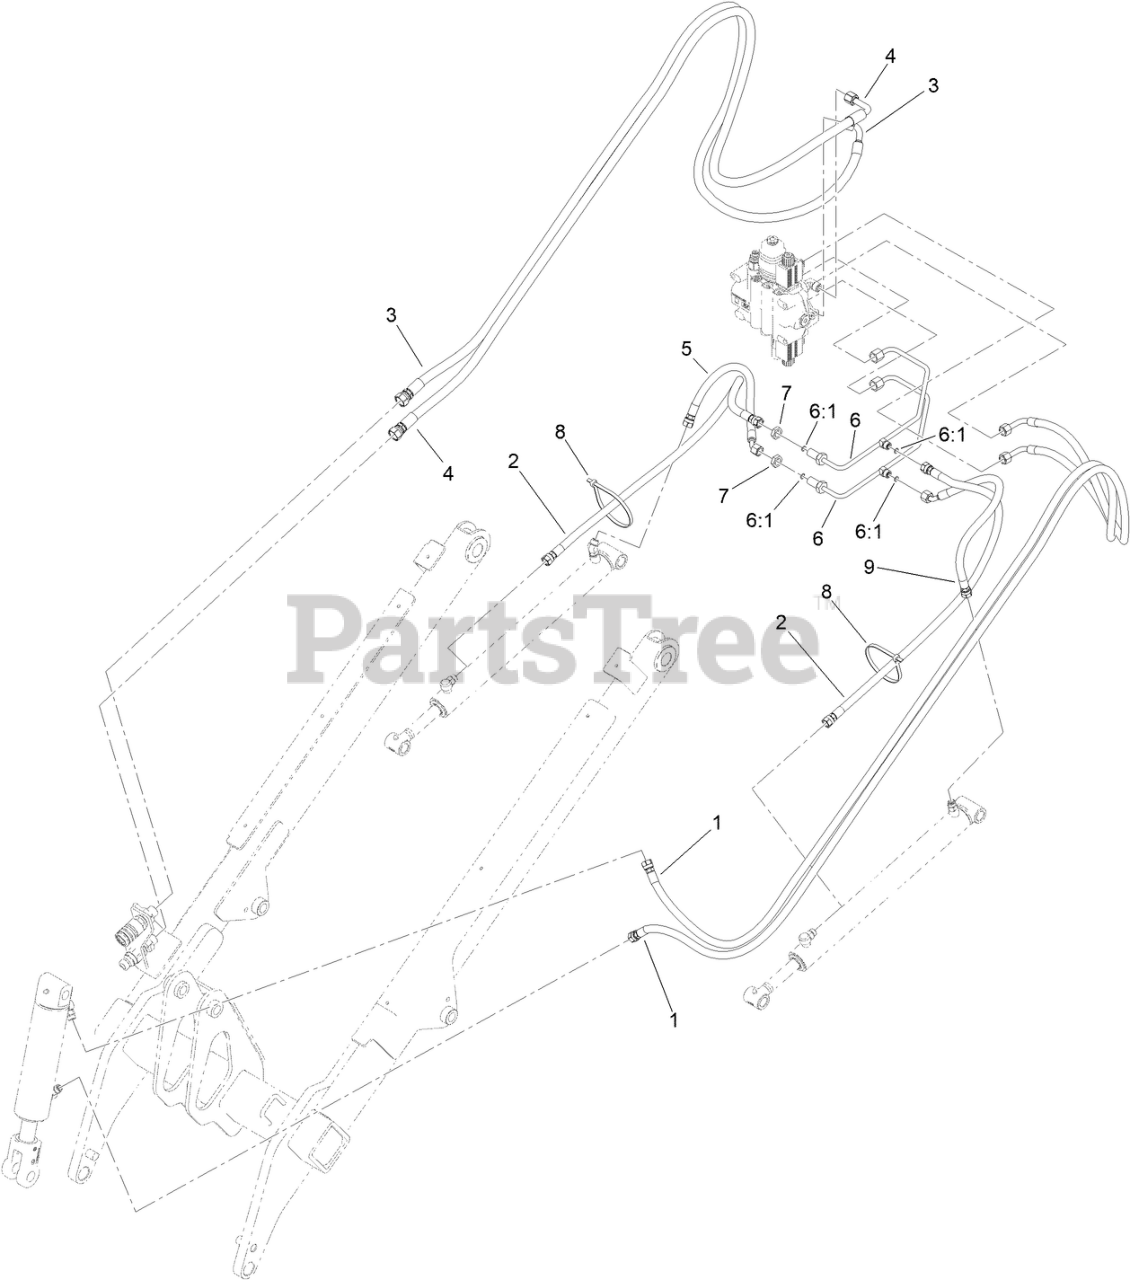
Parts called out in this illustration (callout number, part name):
1	HOSE ASM-HYD
2	HOSE ASM-HYD
3	HOSE ASM-HYD
4	HOSE ASM-HYD
5	HOSE ASM-HYD
6	HYDRAULIC TUBE ASM
6:1	O-RING
7	NUT-LOCK
8	TIE-CABLE
9	HOSE ASM-HYD
